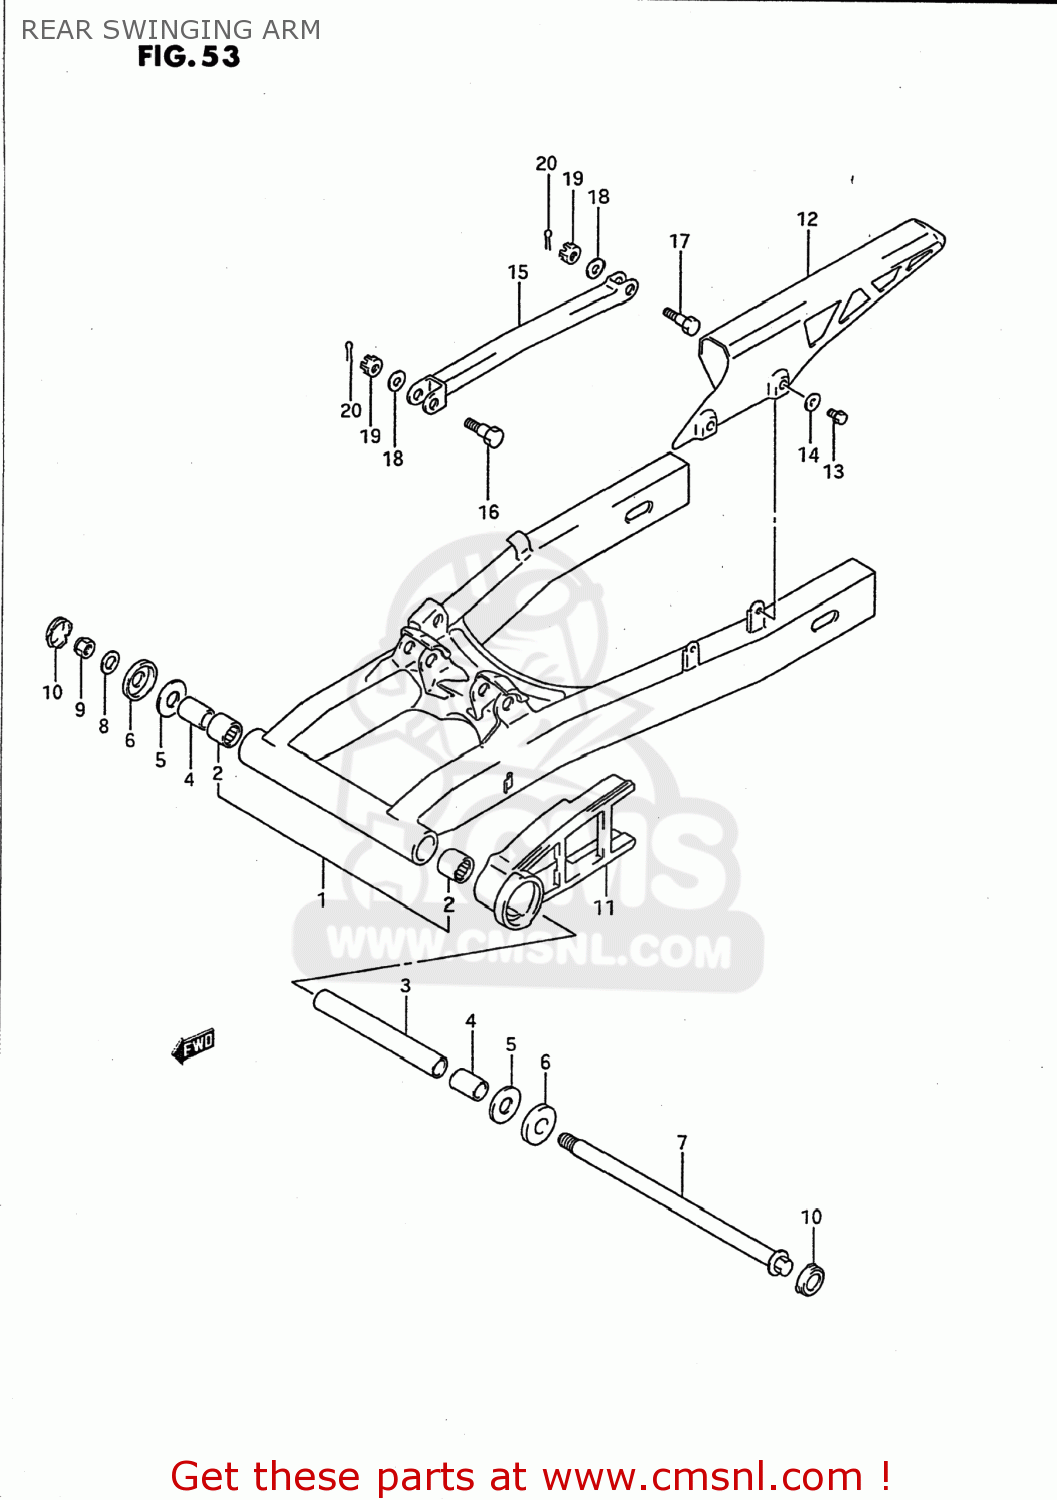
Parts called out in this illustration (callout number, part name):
1	SWING ARM ASSEMBLY,REAR
2	BEARING(22X29X30)
3	SPACER,RR SWGARM PIVOT CTR
4	SPACER,RR SWGARM PIVOT
5	WASHER
6	COVER,RR SWGARM DUST SEAL
7	SHAFT,REAR SWING ARM PIVOT
8	WASHER(14X27X3)
9	NUT
10	CAP,SWINGINGARM PIVOT
11	BUFFER,CHAIN TOUCH DEFENSE
12	CASE,CHAIN
13	BOLT
14	WASHER
15	TORQUE LINK,REAR
16	BOLT(10X41)
17	BOLT(10X35)
18	WASHER (10X18X3.2)
19	NUT
20	PIN 20X20
